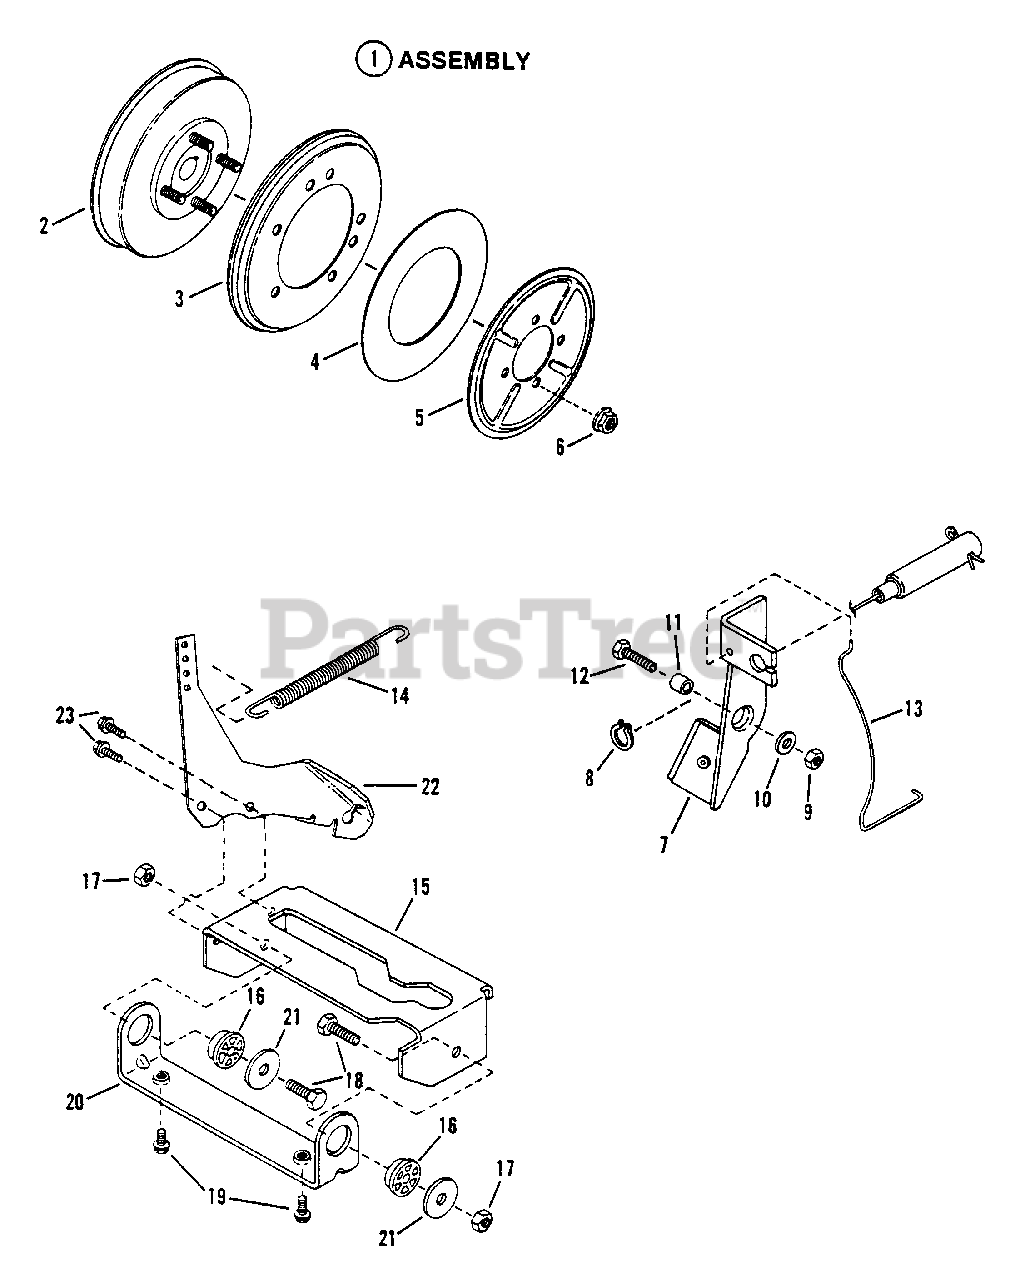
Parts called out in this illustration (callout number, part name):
1	ASSEMBLY, Smooth Clutch
2	HUB, Driven Disc
3	DISC, Driven
4	WASHER, Thrust
5	PLATE
6	NUT, 5/16-18 Hex Flange Lock
7	ASSEMBLY, Brake Lever
8	RING, Retaining
9	NUT, 1/4-28 Hex Top Lock
10	WASHER, 1/4 Flat
11	SPACER
12	SCREW, 1/4-28 x 1" Hex Head Cap
13	SPRING, Brake Return
14	SPRING, Clutch Brake
15	LIFT, Yoke
16	BEARING, Yoke
17	NUT, 5/16-24 Hex Center Lock
18	SCREW, 5/16-24 x 1" Hex Head Cap
19	SCREW, 3/8-16 x 5/8" Self-Tapping
20	COLLAR, Yoke
21	WASHER, 5/16 Flat
22	ARM, Yoke
23	SCREW, 1/4-20 x 3/8" Self-Tapping
